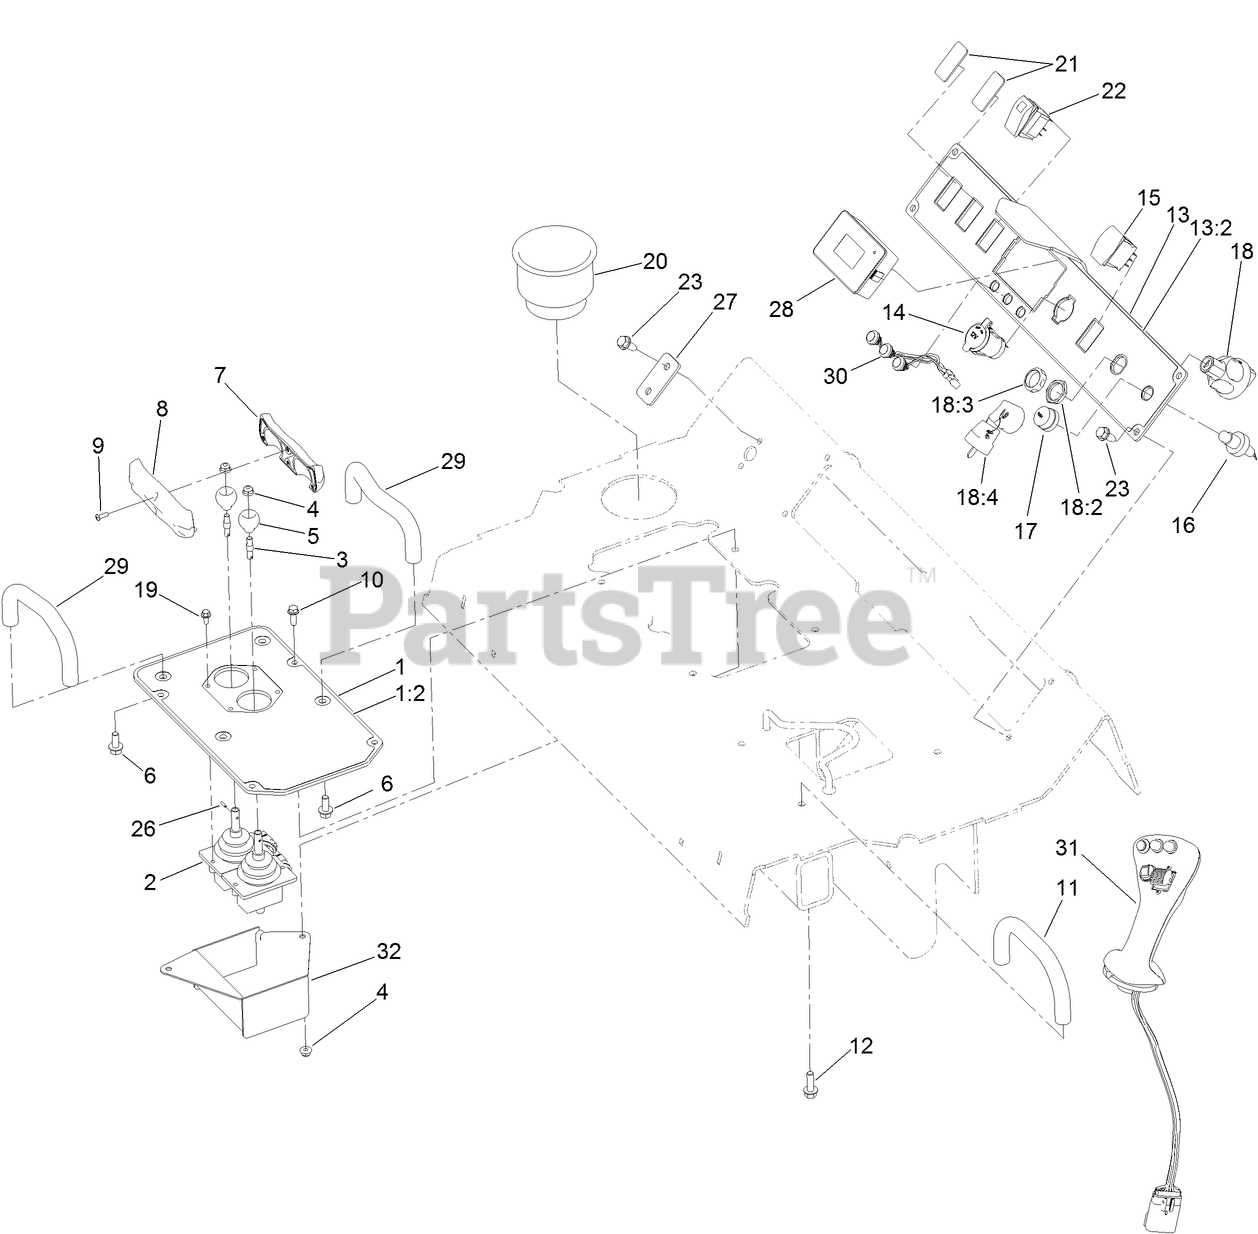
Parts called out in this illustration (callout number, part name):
1	PLATE-CONTROLS, TRACTION
1:2	DECAL-TRACTION
2	LEVER-CONTROL
3	SHAFT-HANDLE
4	NUT-HF
5	BALL-TRACTION
6	SCREW-HHF
7	HANDLE-FRONT
8	HANDLE-REAR
9	SCREW
10	SCREW-HHF
11	BAR-REFERENCE
12	SCREW-HHF
13	PLATE-CONTROLS, MAIN
13:2	DECAL-CONTROLS
14	PORT-POWER, 12V
15	SWITCH
16	SWITCH-HORN
17	NUT-WEATHERPROOF
18	IGNITION SWITCH ASM
18:2	NUT-HEX
18:3	NUT-FACE
18:4	SET-KEY, IGNITION
19	SCREW-HFH
20	CUP-HOLDER
21	BLANK-SWITCH, ROCKER
22	SWITCH
23	SCREW-HWH
26	PIN-ROLL
27	PLATE-BLANK
28	TDM 2002
29	BAR-REFERENCE
30	SWITCH-PUSHBUTTON
31	HANDLE-JOYSTICK
32	COVER-VALVE
